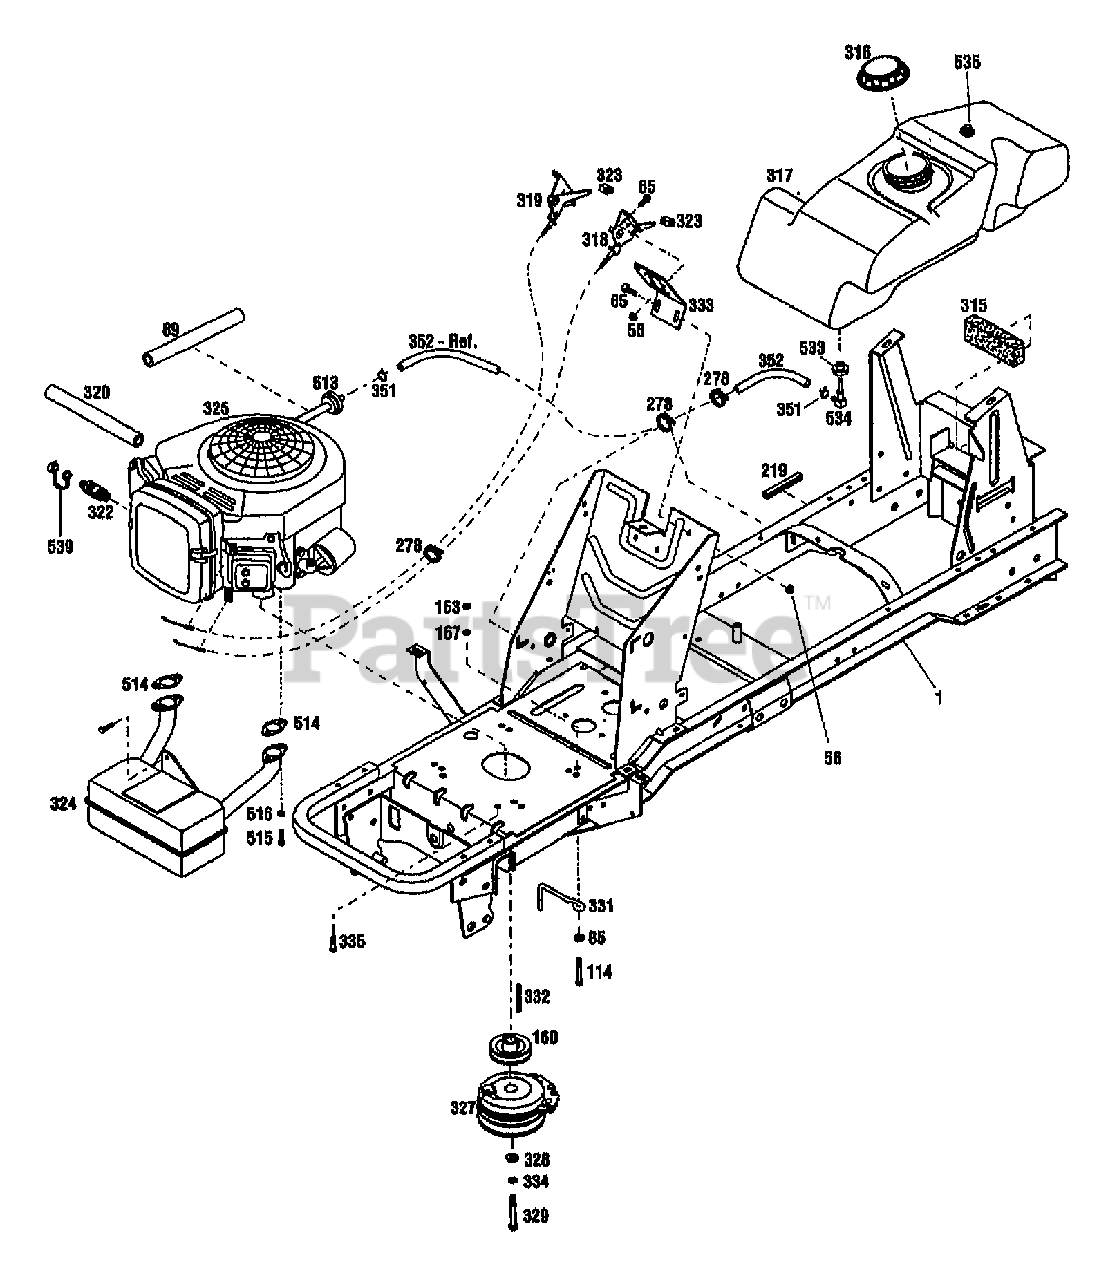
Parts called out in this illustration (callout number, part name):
56	NUT-HF/LK 1/4-20 ZP
65	SCR-HH 1/4-20X.625
85	WASHER-FLAT 3/8 SAE
89	INSULATION-FUEL LINE
114	SCR-THRD FRM 3/8-16X1.50
160	PULLEY-ENGINE
163	NUT-HEX 3/8-16 ZP
167	WASHER-LK .375 @ DEPL
278	TIE-CABLE NYLON BLACK
315	PAD-FUEL TANK
316	CAP-FUEL
317	TANK-FUEL
318	CONTROL-CHOKE
319	THROTTLE-CONTROL
320	HOSE-OIL DRAIN
322	ASSM-OIL VALVE
325	ENGINE, 16HP BRIGGS & STRATTON MODEL 303777
327	CLUTCH-ELECTRIC
328	WASHER-SPEC 1.42X.468X.25 ZP
329	SCR-HH 7/16-20X3.00
331	CLUTCH-RETAINER
332	KEY-.25 SQ X 2.5
333	BRKT-MOUNTING CONTROL
334	WASHER-LK .438 ZP
335	SCR-HH 3/8-16X1.0 THDFM
351	CLAMP-HOSE
352	LINE-FUEL
513	FILTER-FUEL
514	MUFFLER GASKET
515	SCR-HH 1/4-20X1.0
516	WASHER-LK .25 ZP
533	BUSHING-RUBBER
534	ELBOW-90 DEG (FUEL LINE)
535	VENT-FUEL TANK
539	CAP-OIL DRAIN
